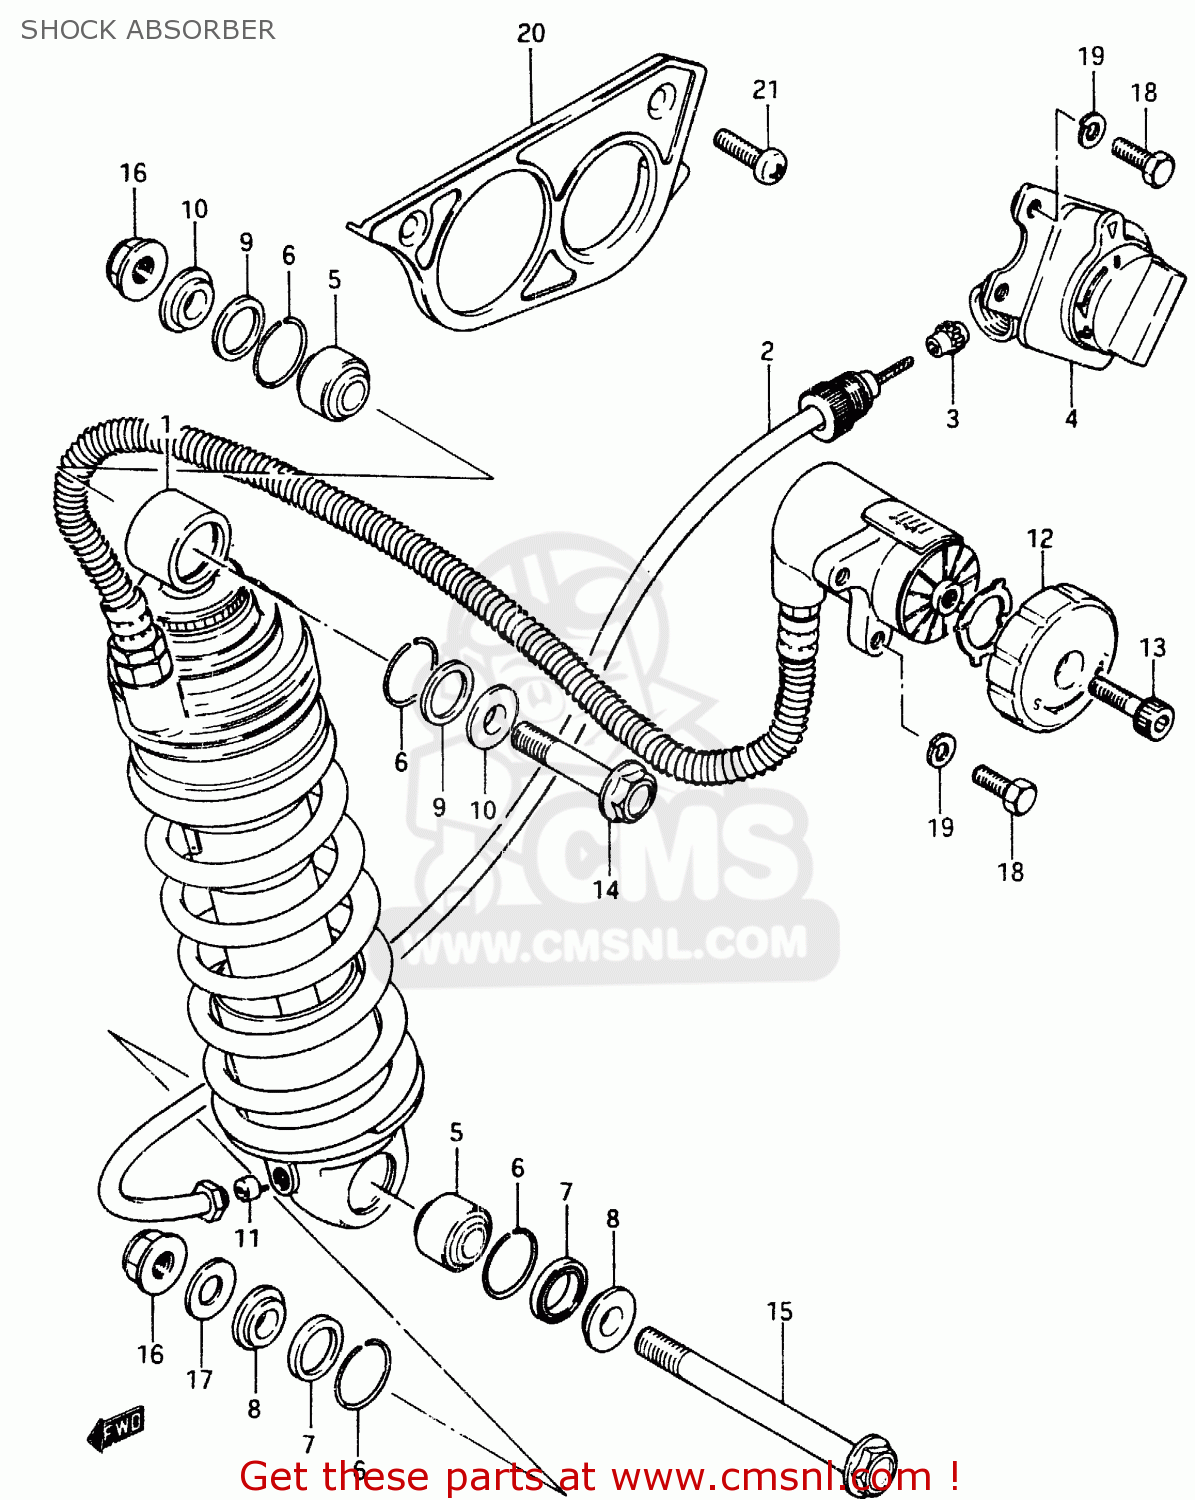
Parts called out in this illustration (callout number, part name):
1	MONO GSX750ESG
2	CABLE,CONTROL
3	GEAR
4	ADJUSTER
5	BEARING,REAR SHOCK ABSORBER
6	RING
7	DUST SEAL
8	SPACER
9	SEAL,DUST
10	COLLAR
11	CAM,DAMPER ADJUSTER
12	PLATE,LEVELING
13	BOLT
14	BOLT(10X50)
15	BOLT(10X115)
16	NUT
17	WASHER
18	BOLT 6X16
19	WASHER,LOCK
20	COVER,REAR SHOCK ABSORBER ADJUSTER
21	SCREW
